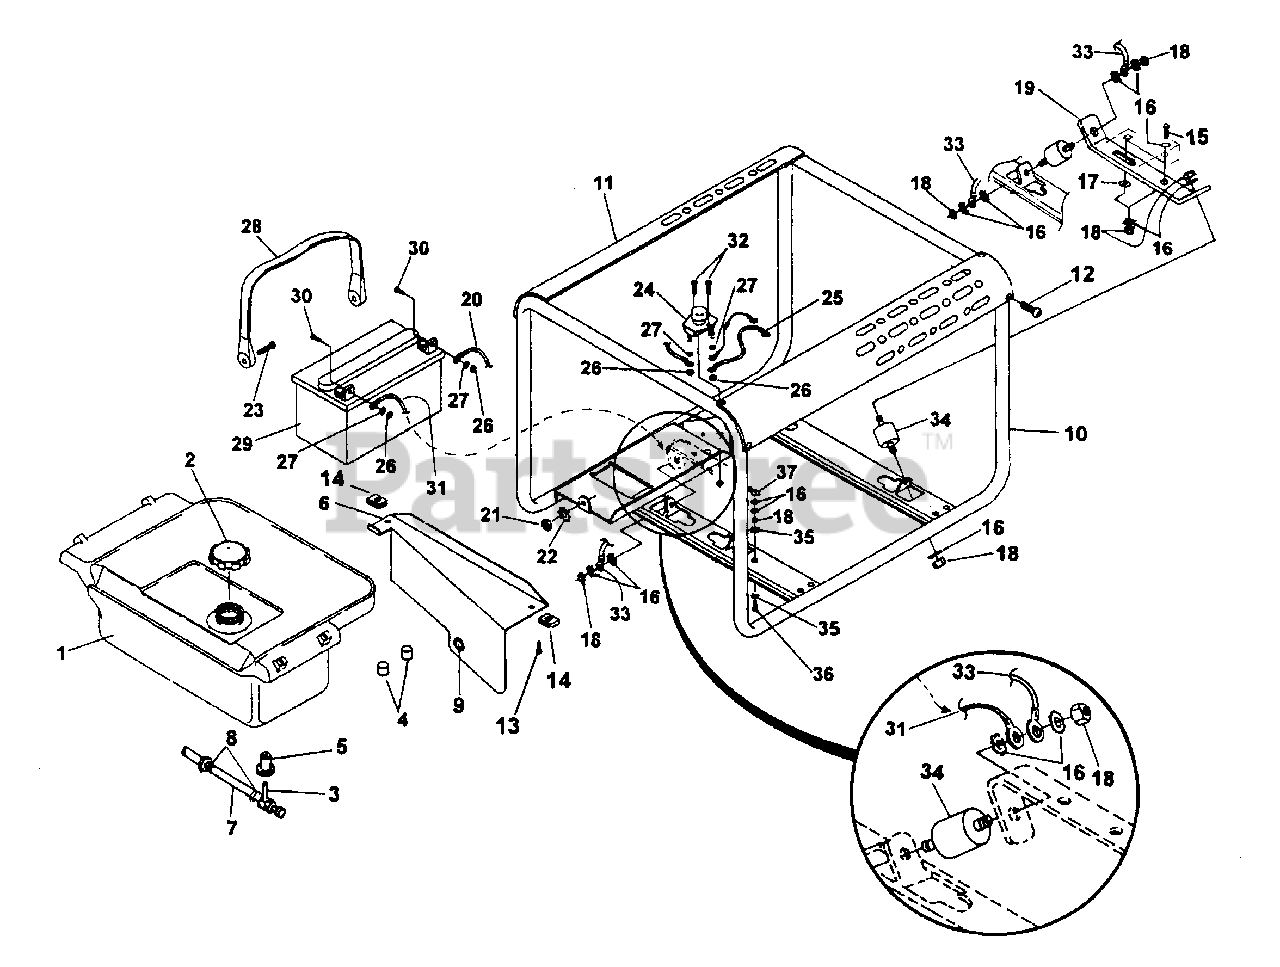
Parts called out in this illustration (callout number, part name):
1	FUEL TANK (5 Gal.)
2	FUEL CAP (2 1/4" dia.)
3	VALVE-Fuel
4	PAD-Fuel Tank
5	BUSHING
6	SHIELD-Fuel Tank
7	FUEL LINE
8	CLIP-Hose
9	BUSHING-Snap In
10	ROLL CAGE
11	BRACE-Tank Support
12	SCREW-Torx (10-24 X 1/2")
13	SCREW-Pan Hd. (8-32 X 3/8")
14	NUT-Hi Speed
15	SCREW-Hex Hd. (5/16-18 X 2")
16	WASHER-Lock (int.)
17	WASHER-Flat
18	NUT-Hex (5/16-18)
19	SUPPORT-Engine
20	CABLE-Battery (Red, Pos.)
21	NUT-Hex (10-32)
22	WASHER-Lock
23	SCREW-Shoulder (10-32 X 1/4")
24	SWITCH-Starter
25	BATTERY CABLE (Red, to Switch)
26	NUT-Hex (10-32)
27	WASHER-Lock
28	STRAP-Battery Hold Down
29	BATTERY (12 Volt)
30	SCREW-Hex Hd. (1/4-20 X 5/8")
31	BATTERY CABLE (Black, to Ground)
32	SCREW-Hex Hd. (1/4-20 X 1/2")
33	GROUND STRAP
34	ISOLATOR
35	WASHER-Lock (ext./int.)
36	SCREW-Hex Hd. (5/16-18 X 1 1/2")
37	NUT-Wing
